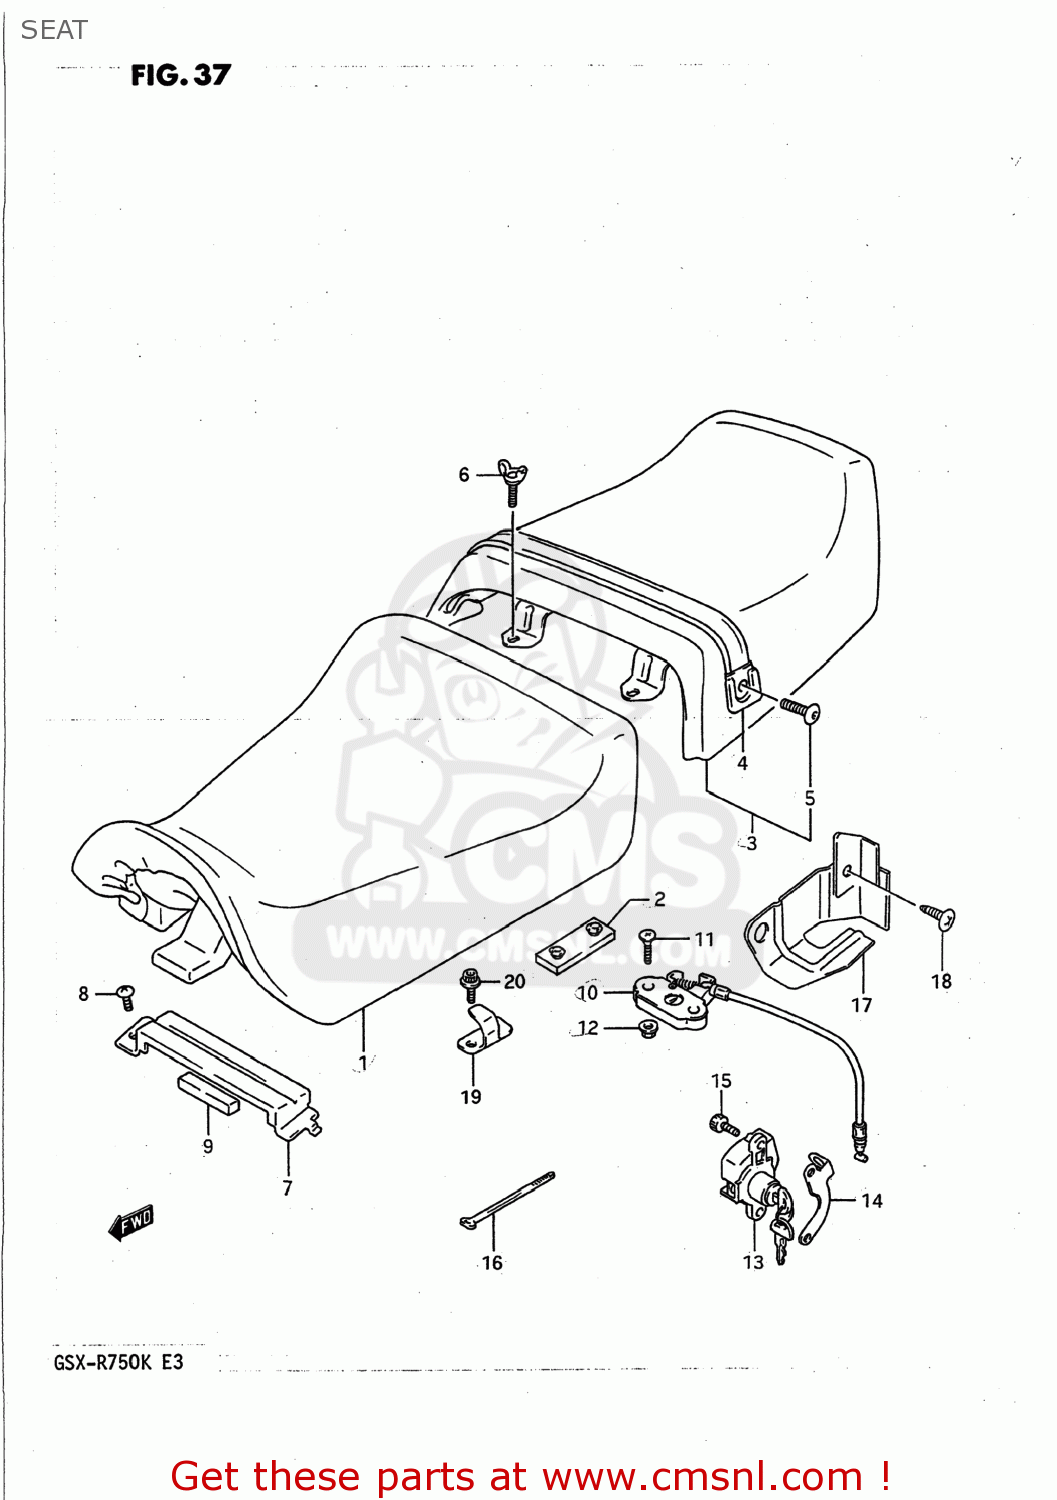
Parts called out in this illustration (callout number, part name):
1	SEAT ASSEMBLY
2	CUSHION
3	SEAT ASSEMBLY,PILLION
4	BAND,SEAT
5	BOLT
6	BOLT
7	PLATE,SEAT SUPPORT RR
8	SCREW
9	CUSHION,PLATE SEAT SPRING
10	BRACKET,SEAT SUPPORT RR
11	SCREW
12	NUT
13	LOCK SET,SEAT
14	PLATE,SEAT LOCK
15	BOLT
16	CLAMP
17	PLATE,SEAT LOCK CABLE
18	BOLT
19	HOLDER,HELMET
20	BOLT
